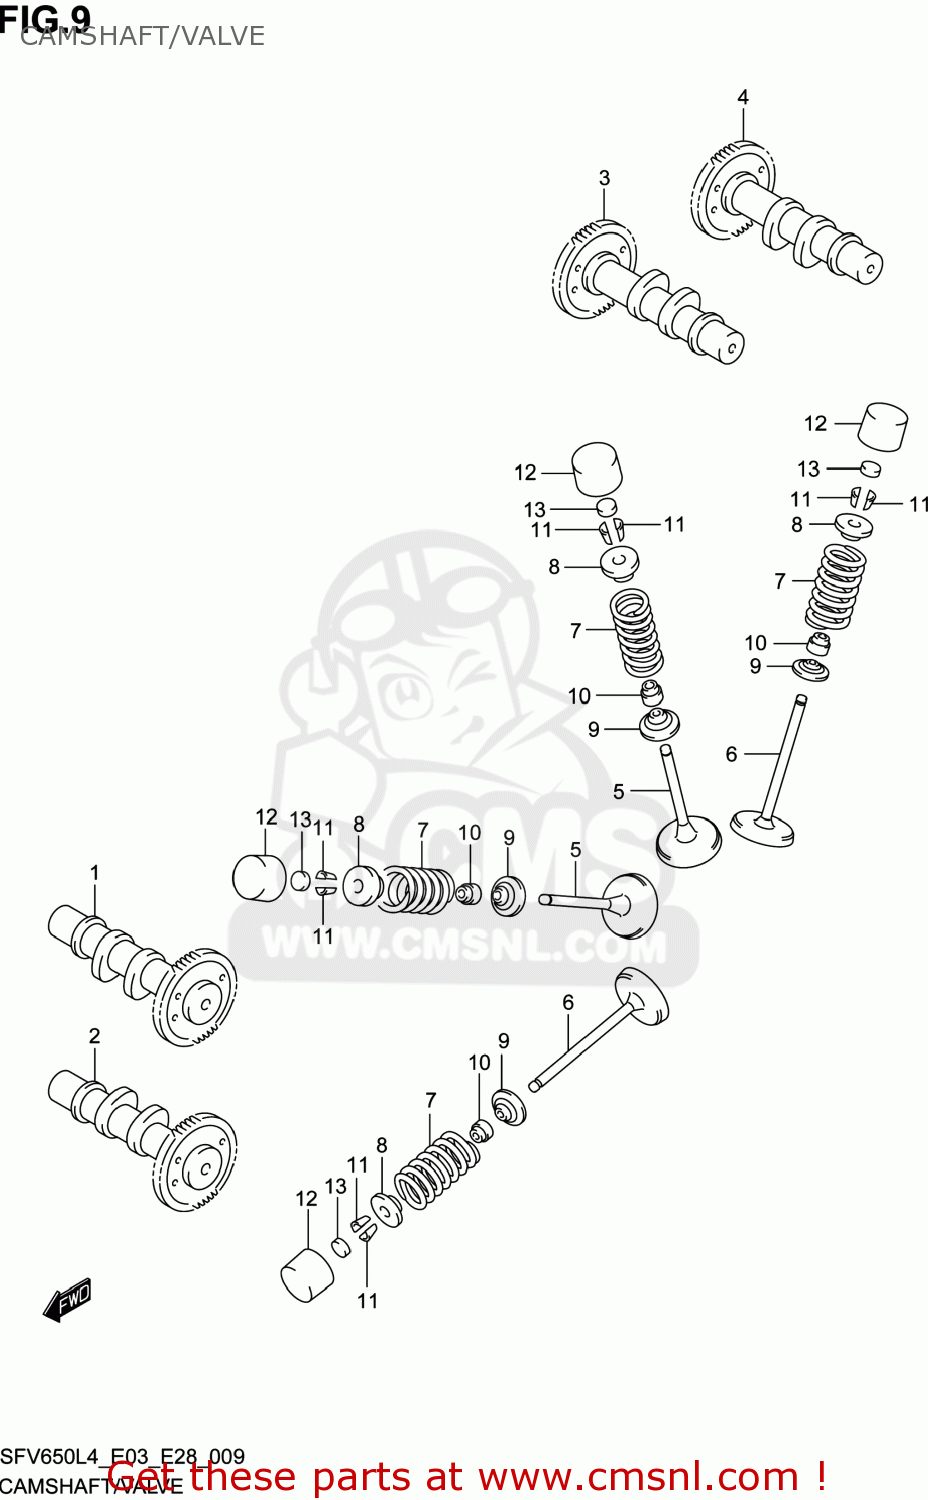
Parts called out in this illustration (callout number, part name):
1	CAMSHAFT,INTAKE FR
2	CAMSHAFT,EXHAUST FR
3	CAMSHAFT,INTAKE RR
4	CAMSHAFT,EXHAUST RR
5	VALVE,INTAKE
6	VALVE,EXHAUST
7	SPRING,VALVE
8	RETAINER,VALVE SPRING
9	SEAT,VALVE SPRING
10	SEAL,OIL(4.5X10X8)
11	COTTER VALVE
12	TAPPET
13	SHIM,TAPPET
14	SHIM SET,TAPPET
15	CASE,TAPPET SHIM
